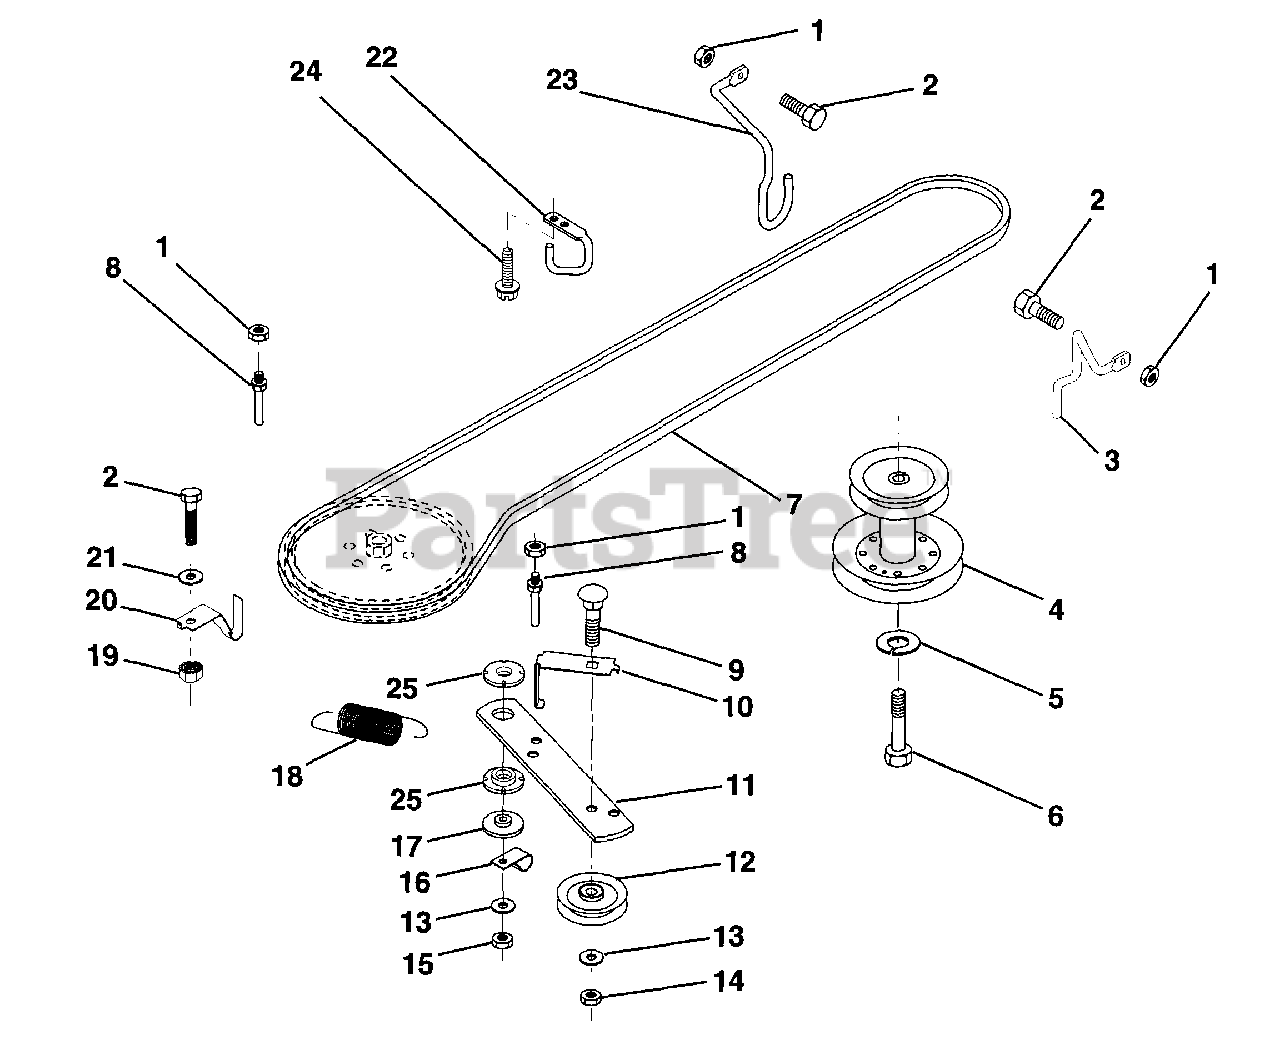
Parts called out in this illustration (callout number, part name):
1	Nut, Crownlock 5/16-18
2	Bolt, Hex Hd 5/16-18 UNC x 3/4
3	Keeper,Mower Drive, R. H.
4	Pulley, Engine
5	Washer, Lock 7/16
6	Bolt Hex 7/16-20 Gr. 5
7	Traction, V-Belt Drive
8	Keeper, T/A Ground Drive Belt
9	Bolt, Carr. 3/8-16 UNC x 1-1/2
10	Keeper, Belt Ground Drive Idler
11	Arm, Ground Drive Clutch
12	Idler, Flat
13	Washer 13/32 x 13/16 x 16 Ga.
14	Nut, Centerlock 3/8-16 UNC
15	Nut, Crownlock 3/8-16 UNC
16	Clip, Insulated
17	Spacer, Retainer
18	Spring Extension
19	Nut, Keps 5/16-18 UNC
20	Keeper, T/A Ground Drive Belt
21	Washer 11/32 x 5/8 x 16 Ga.
22	Keeper, Frame Ground Drive Belt
23	Keeper, Mower Drive, L. H.
24	Screw, Thd. Cut 1/4-20 x 1/2
25	Bushing Nylon Collered
